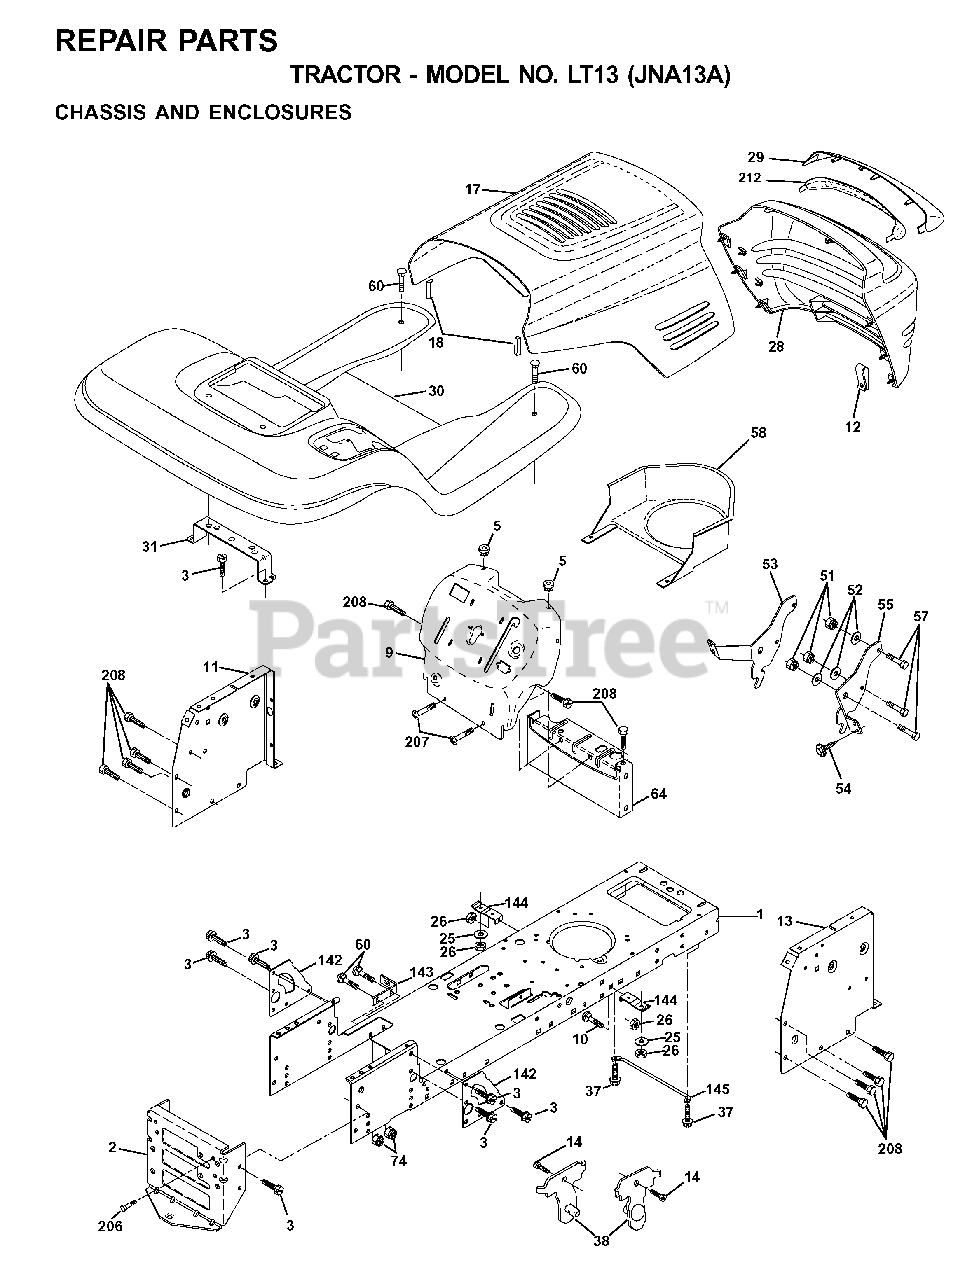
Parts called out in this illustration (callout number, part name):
1	CHASSIS STAMPING
2	DRAWBAR, 12GA
3	SCREW 3/8-16X3/4
5	BUMPER.RUBBER.HOOD
10	BOLT D
11	PANEL DASH LH
13	PANEL DASH RH
18	BUMPER HOOD T
25	WASHER
26	NUT
38	BRACKET.ASM.PIVOT.MOWER.REAR
51	LOCKNUT
53	BRACKET.GRILLE.LH
57	BOLT
58	AIR DUCT P/L/LT
64	DASH LOWER
74	LOCKNUT
142	PLATE
143	BRACKET, SWAY BAR
144	BRACKET FOOTREST
145	ROD PIVOT CHASSIS/HOOD
206	SHOULDER BOLT 5/16-18TT
207	SCREW, 5/16-18 X 1/2
208	SCREW 3/8-16X1/2
